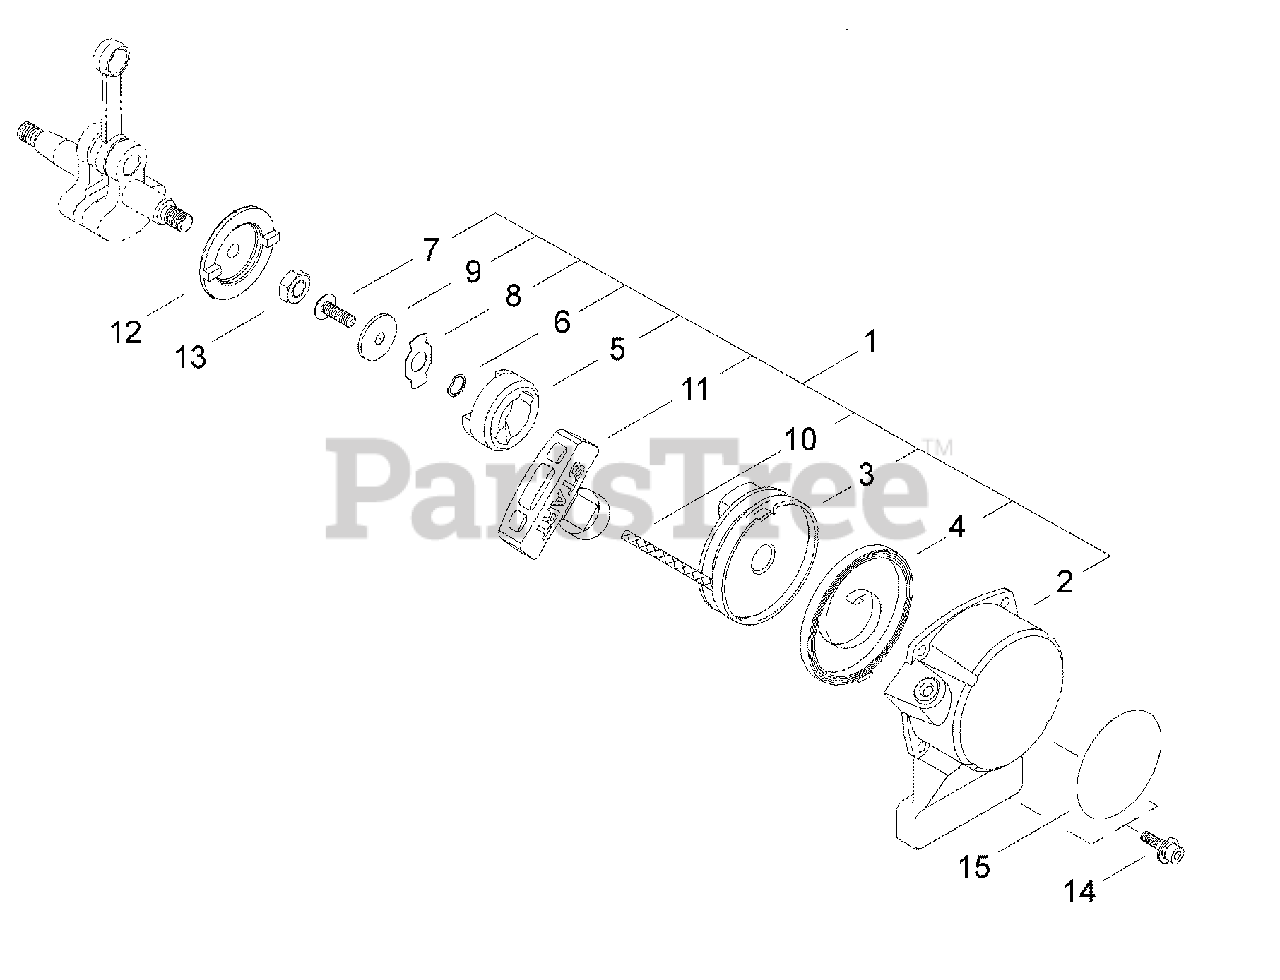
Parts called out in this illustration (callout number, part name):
1	STARTER ASSY, RECOIL
2	CASE, RECOIL STARTER
3	REEL, ROPE
4	SPRING, RECOIL
5	PAWL, STARTER
6	WASHER, WAVE
7	SCREW 5 MM
8	RETAINER
9	WASHER 5 MM
10	ROPE, STARTER
11	GRIP, STARTER
12	PULLEY, STARTER
13	NUT M8×1
14	BOLT M4×16
15	LABEL, RECOIL C4
